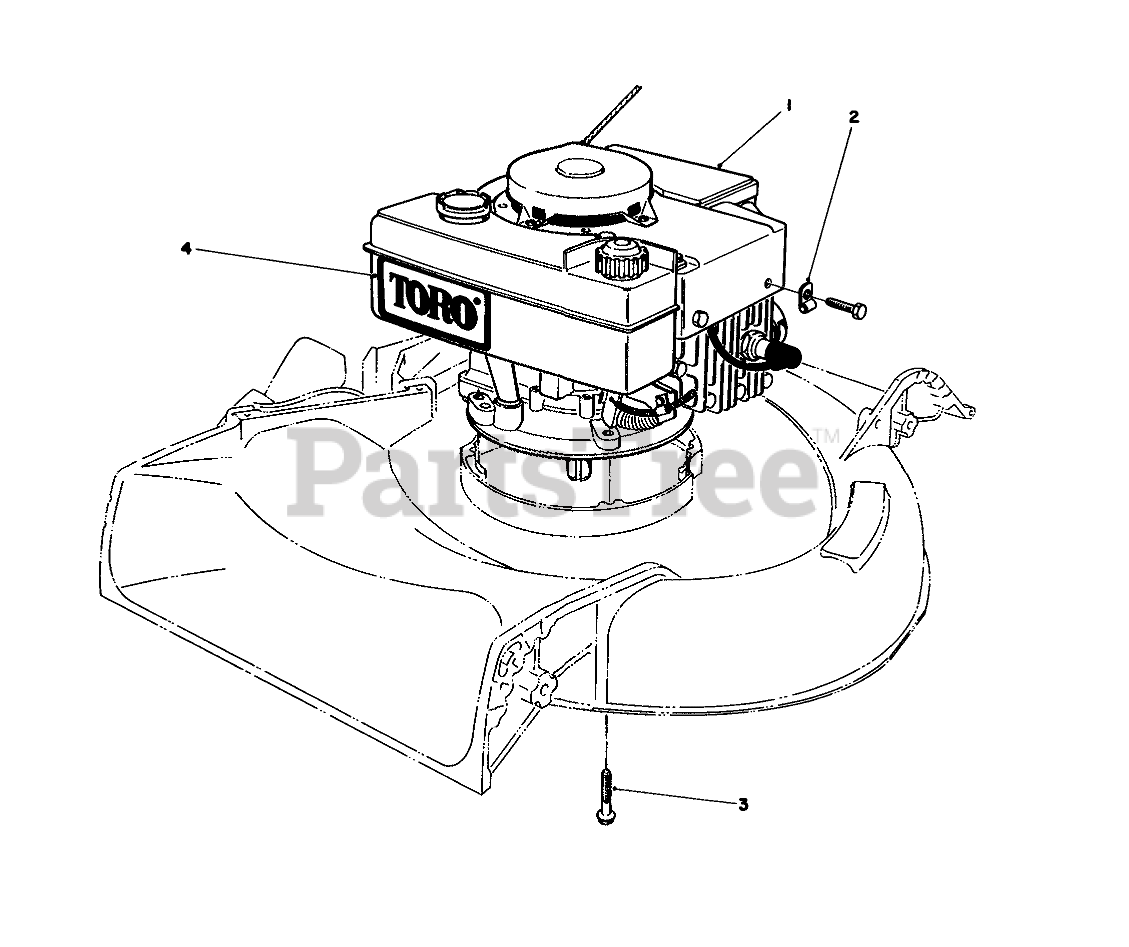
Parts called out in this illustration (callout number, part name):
1	Engine
2	CLAMP
3	3/8-16 X 2-3/4 CAPSCR
4	Decal Tow
